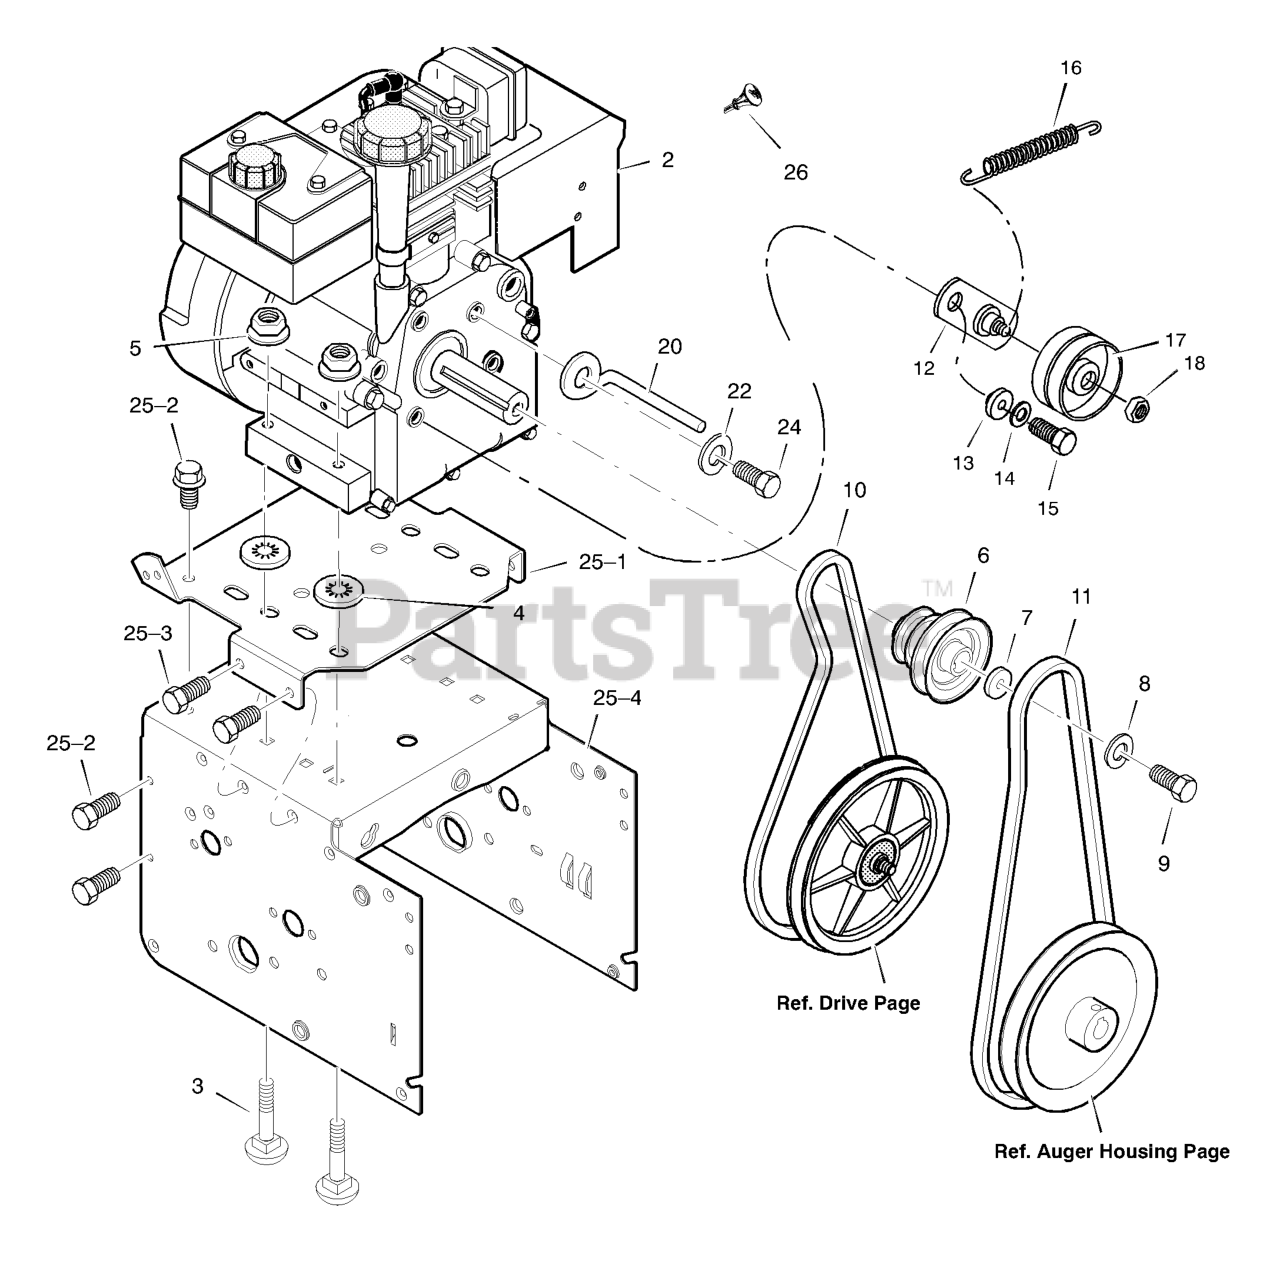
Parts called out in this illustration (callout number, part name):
2	ENGINE
3	BOLT, CARRIAGE 5/16-18
4	RETAINER, PUSH
5	NUT 5/16-18
6	PULLEY, ENGINE
7	WASHER
8	WASHER .38ID
9	SCREW, 3/8-24 x 1.00
10	BELT, V 3L
11	BELT, V 4L
12	BRACKET ASSEMBLY, IDLER
13	BUSHING, IDLER BRACKET
14	WASHER, SPLIT
15	SCREW 5/16-24 X 0.75
16	SPRING, IDLER TRACTION DRIVE
17	PULLEY, IDLER
18	NUT, JAM 3/8-16
20	GUIDE, BELT
22	WASHER .31X.58X.08
24	SCREW, 5/16-24 x 0.75
25-1	PLATE, ENGINE MOUNT
25-2	SCREW, TAP 1/4-20 X .63
25-3	SCREW, TAP 5/16-18 X .50
25-4	FRAME, MOTOR BOX
26	KEY, ENGINE -BRIGGS
